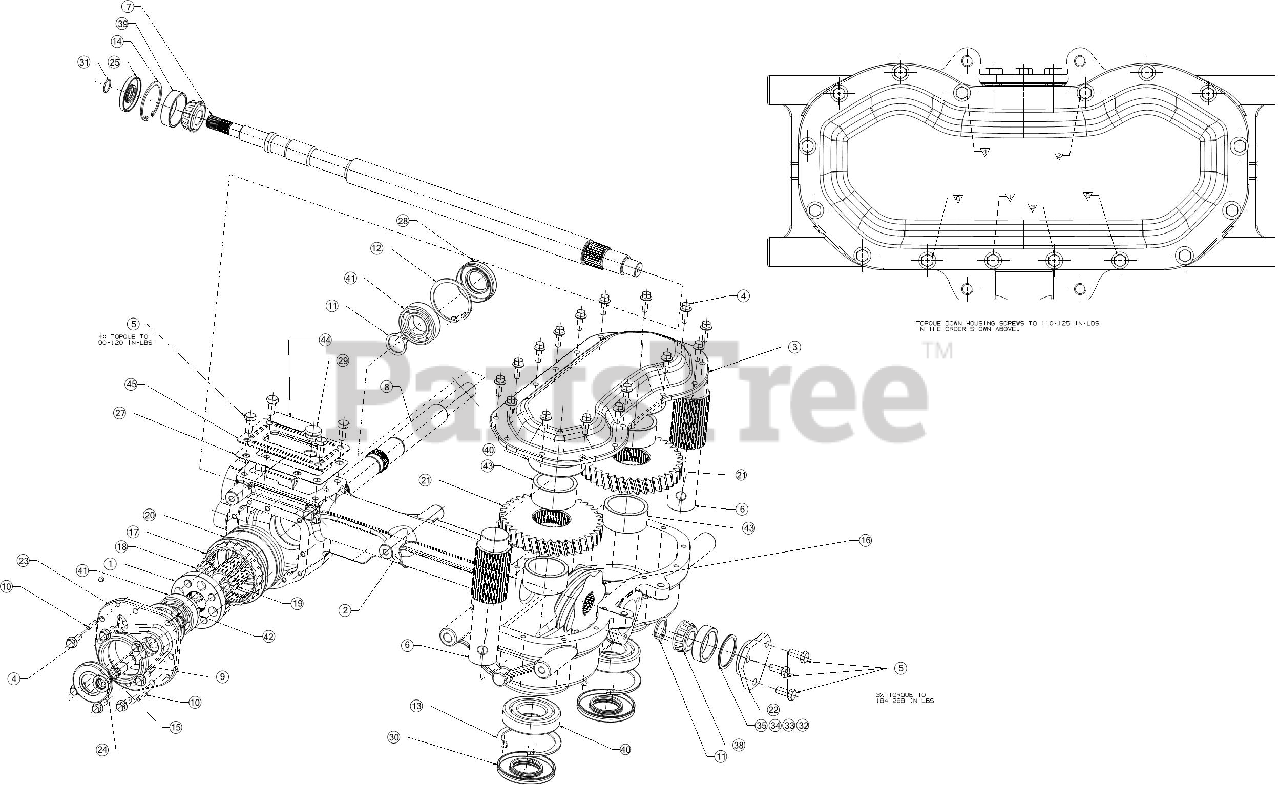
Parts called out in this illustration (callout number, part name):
1	PLANETARY CARRIER ASSEMBLY
2	TRANSMISSION HOUSING
3	TRANSMISSION COVER
4	SCREW 1/4-20 x .75 GR5
5	SCREW 5/16-18 x .75 GR5
6	TINE SHAFT
7	WORM DRIVE SHAFT
8	WHEEL SHAFT
9	NEUTRAL DRIVE SHAFT
10	DOWEL PIN
11	RETAINING RING
12	RETAINING RING
13	RETAINING RING
14	RETAINING RING
15	SNAP RING FOR .500
16	WORM GEAR 7T
17	RING GEAR 48T
18	PLANETARY GEAR 12T
19	SUN GEAR 24T
20	WORM GEAR 61T
21	TINE SHAFT GEAR- 38T
22	BEARING COVER
23	TILLER HOUSING COVER
24	OIL SEAL .5000 x .8750 x .2500
25	OIL SEAL .750 SHF x 1.783
26	SEALANT
27	GEAR HOUSING GASKET
28	OIL SEAL 1.00 SHF x 2.00 BORE
29	RUBBER OIL PLUG
31	WIRE RING
32	FLAT WASHER 1.500X1.750X.062
33	FLAT WASHER 1.500X1.750X.005
34	FLAT WASHER 1.500X1.750X.030
35	FLAT WASHER 1.500X1.750X0.010
36	OIL
37	GREASE
38	BEARING CONE
39	BEARING CUP
40	BALL BEARING
41	BALL BEARING
42	SPACER 1.010 x 1.500 x 0.175
43	SPACER 1.780 x 2.180 x 1.010
44	LABEL
45	TRANSMISSION COVER
